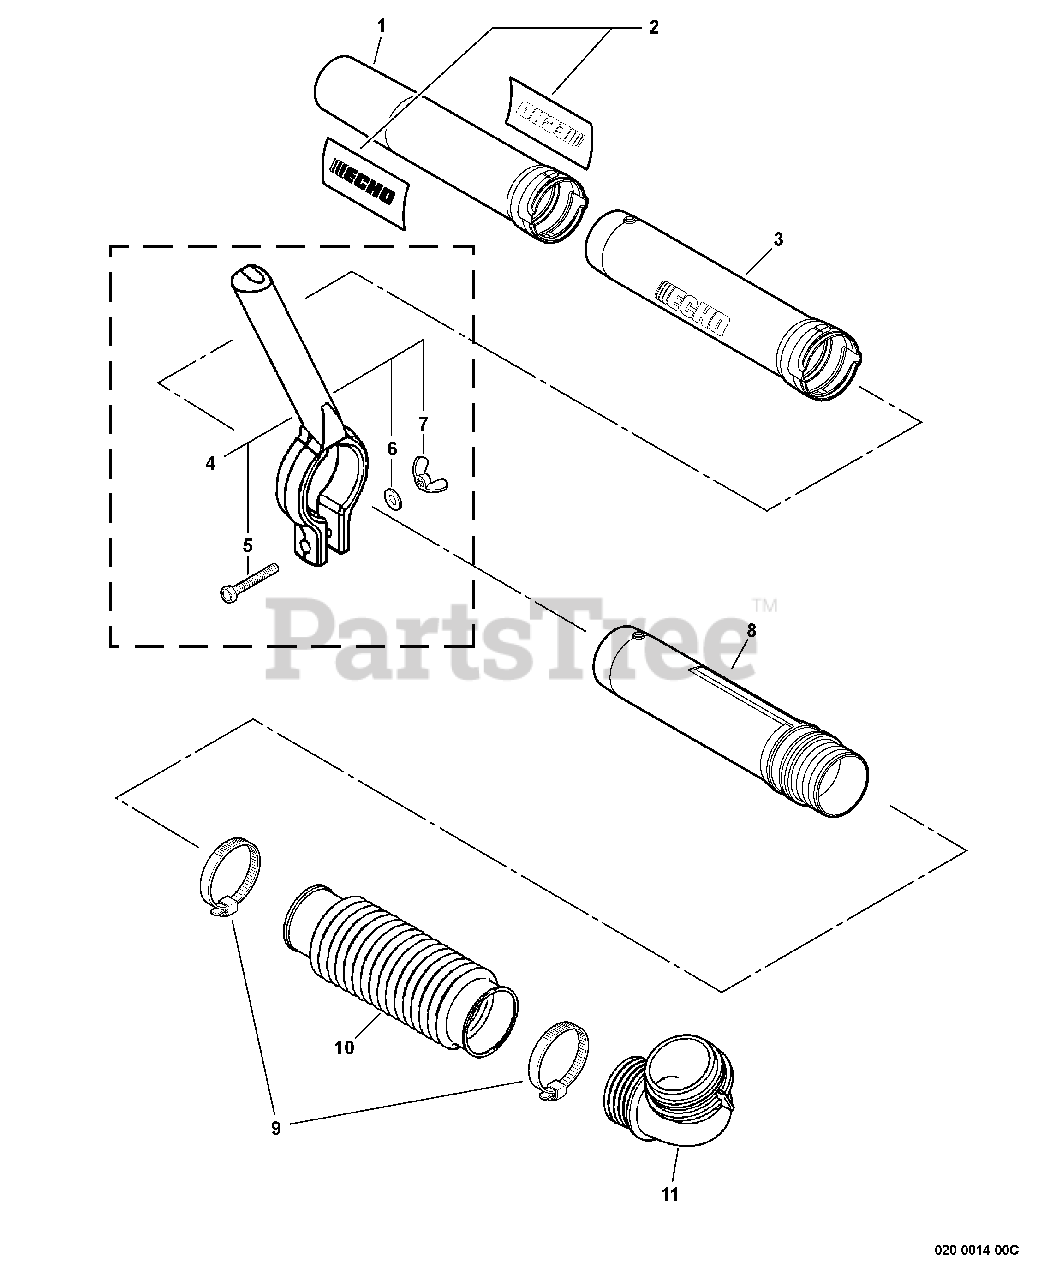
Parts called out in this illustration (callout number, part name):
1	TUBE, BLOWER - STRAIGHT
2	LABEL, ECHO BLOWER TUBE
3	TUBE, BLOWER - STRAIGHT
4	HANDLE ASSY, PB LARGE
5	BOLT 6×45
6	WASHER 6.5×11.5×0.8
7	NUT, WING 6
8	TUBE, BLOWER - SWIVEL
9	CLAMP 58.7 MM / 82.5 MM
10	TUBE, FLEXIBLE
11	PIPE
